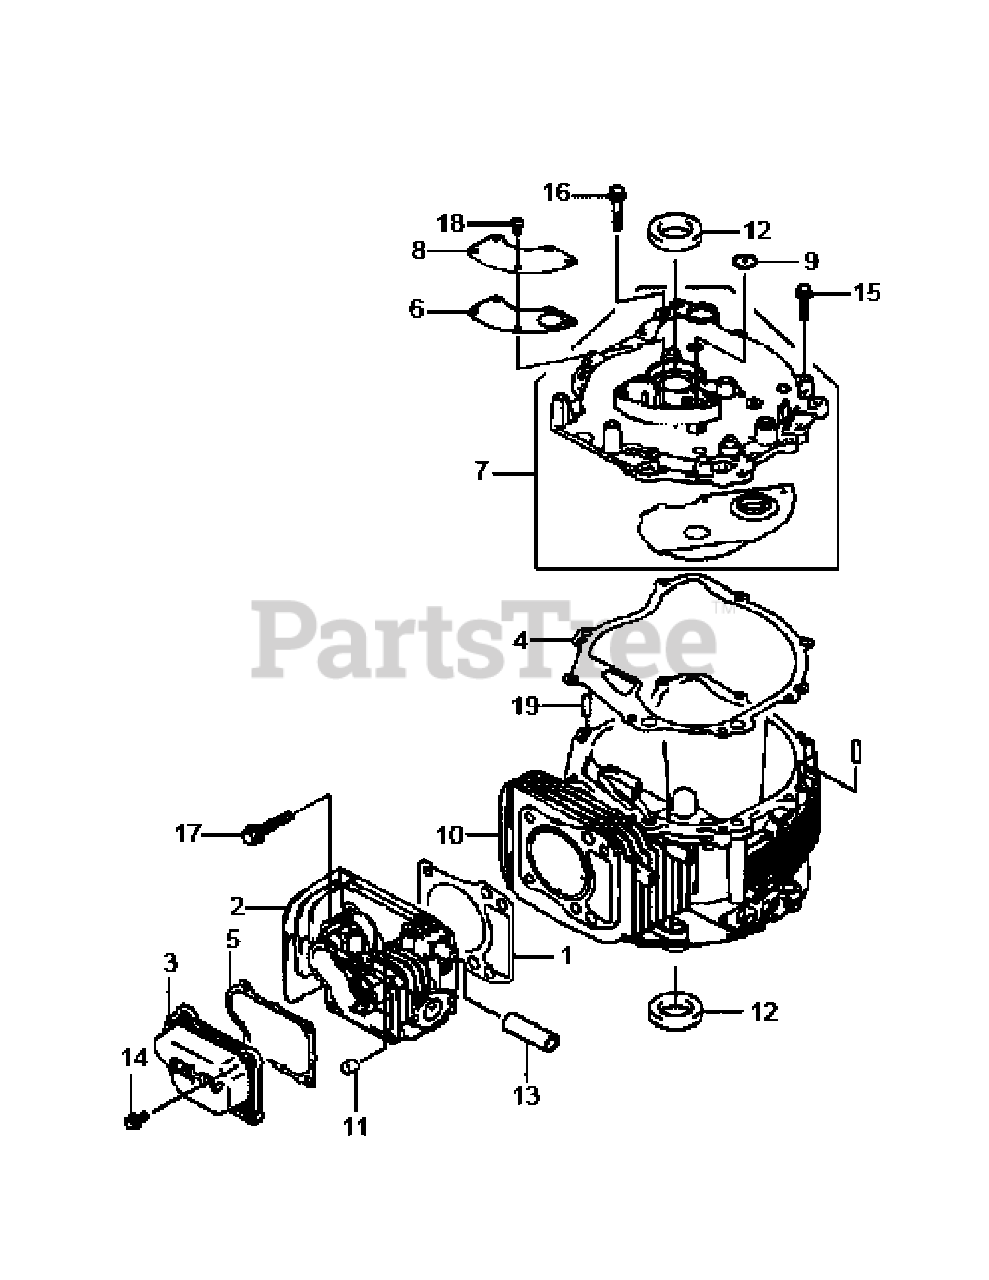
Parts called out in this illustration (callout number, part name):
1	Head Gasket
2	Cylinder Head
3	Rocker Case
4	Cover Gasket
5	Rocker Case Gasket
6	Breather Gasket
7	Cover-Complete
8	Breather Cover
9	Breather Valve
10	Crankcase-Complete
13	Tube, 12x16x49
14	Flanged Bolt
15	Flanged Bolt
16	Flanged Bolt
17	Flanged Bolt
